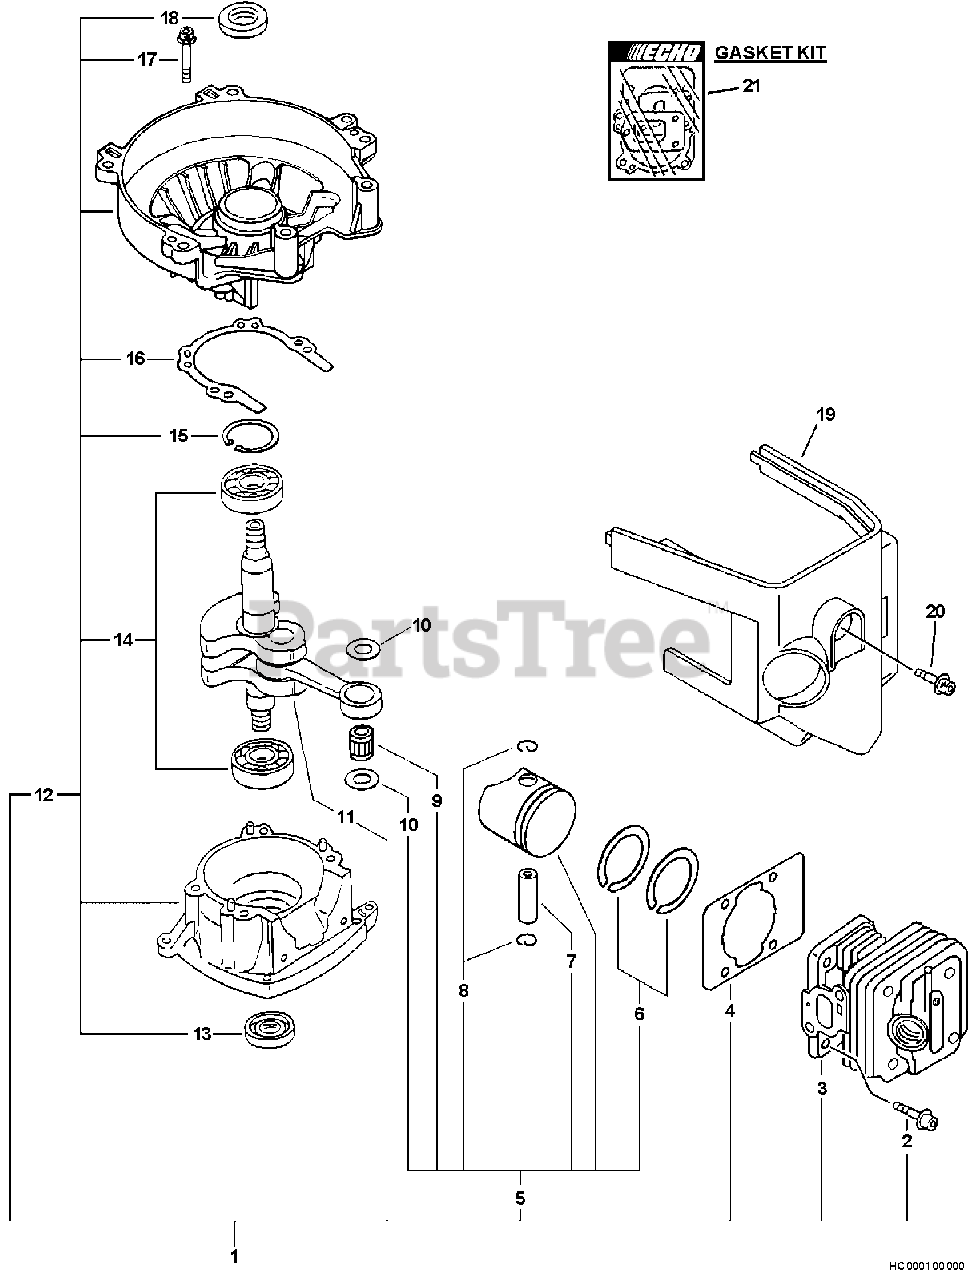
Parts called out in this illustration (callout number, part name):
1	SHORT BLOCK -- SB1046
2	SCREW - 5X22
3	CYLINDER
4	GASKET, CYLINDER
5	PISTON KIT
6	RING, PISTON
7	PIN, PISTON
8	RING, RETAINING
9	BEARING, NEEDLE
10	SPACER, PISTON
11	CRANKSHAFT ASSY
12	CRANKCASE KIT
13	SEAL, OIL
14	BEARING, BALL - 6001C3
15	RING, RETAINING - 28
16	GASKET, CRANKCASE
17	SCREW - 5X25
18	SEAL, OIL - 12
19	COVER, ENGINE
20	SCREW - 5X16
21	GASKET KIT
